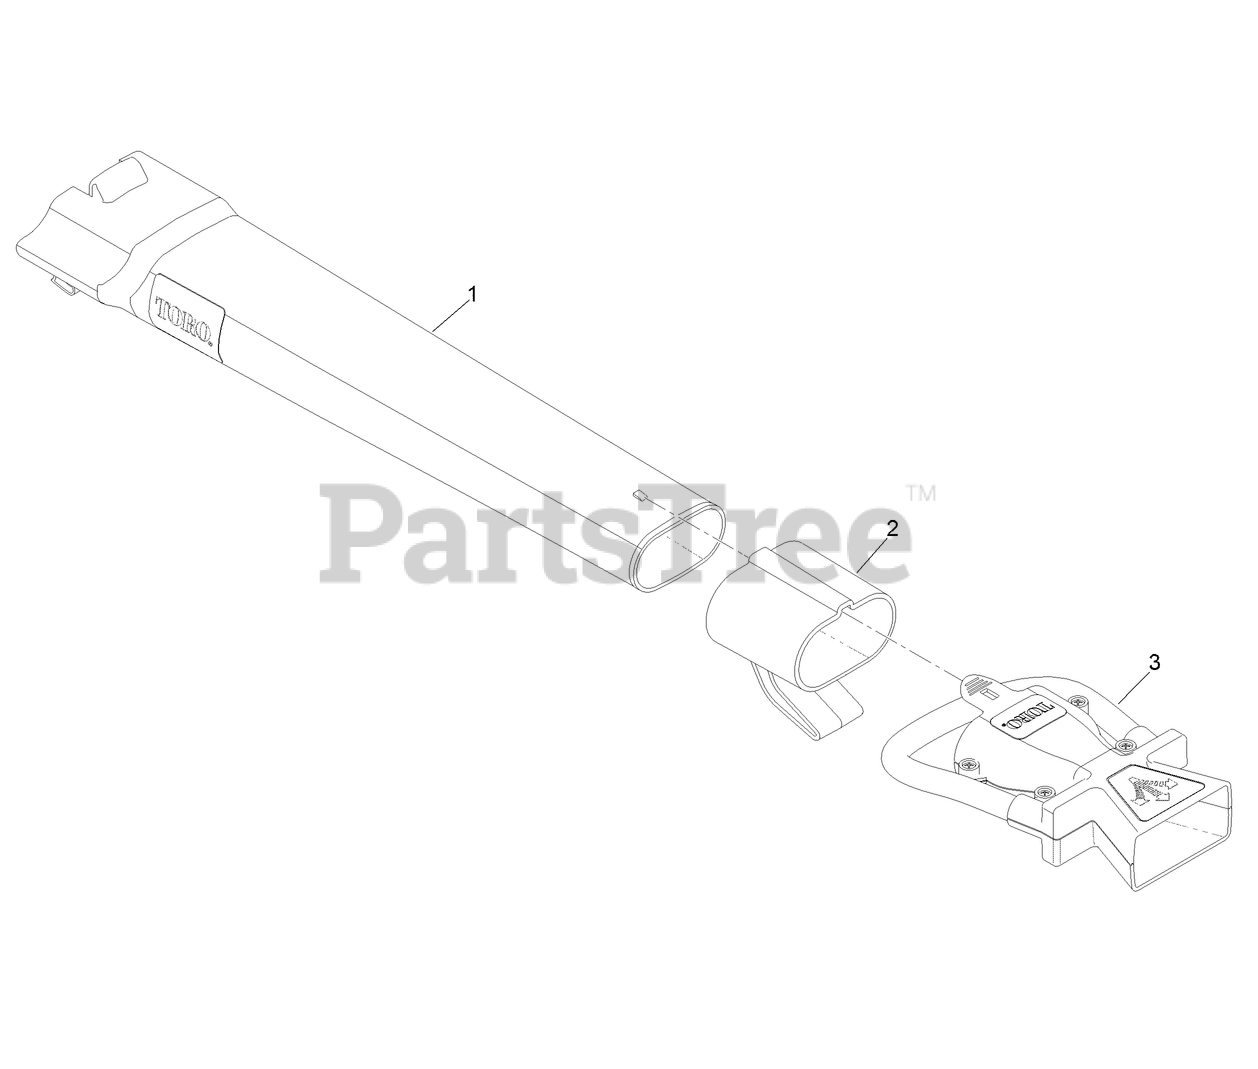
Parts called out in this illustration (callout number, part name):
1	TUBE-BLOWER
2	ADAPTER-WRAP, CORD
3	OSCILLATOR NOZZLE ASM
